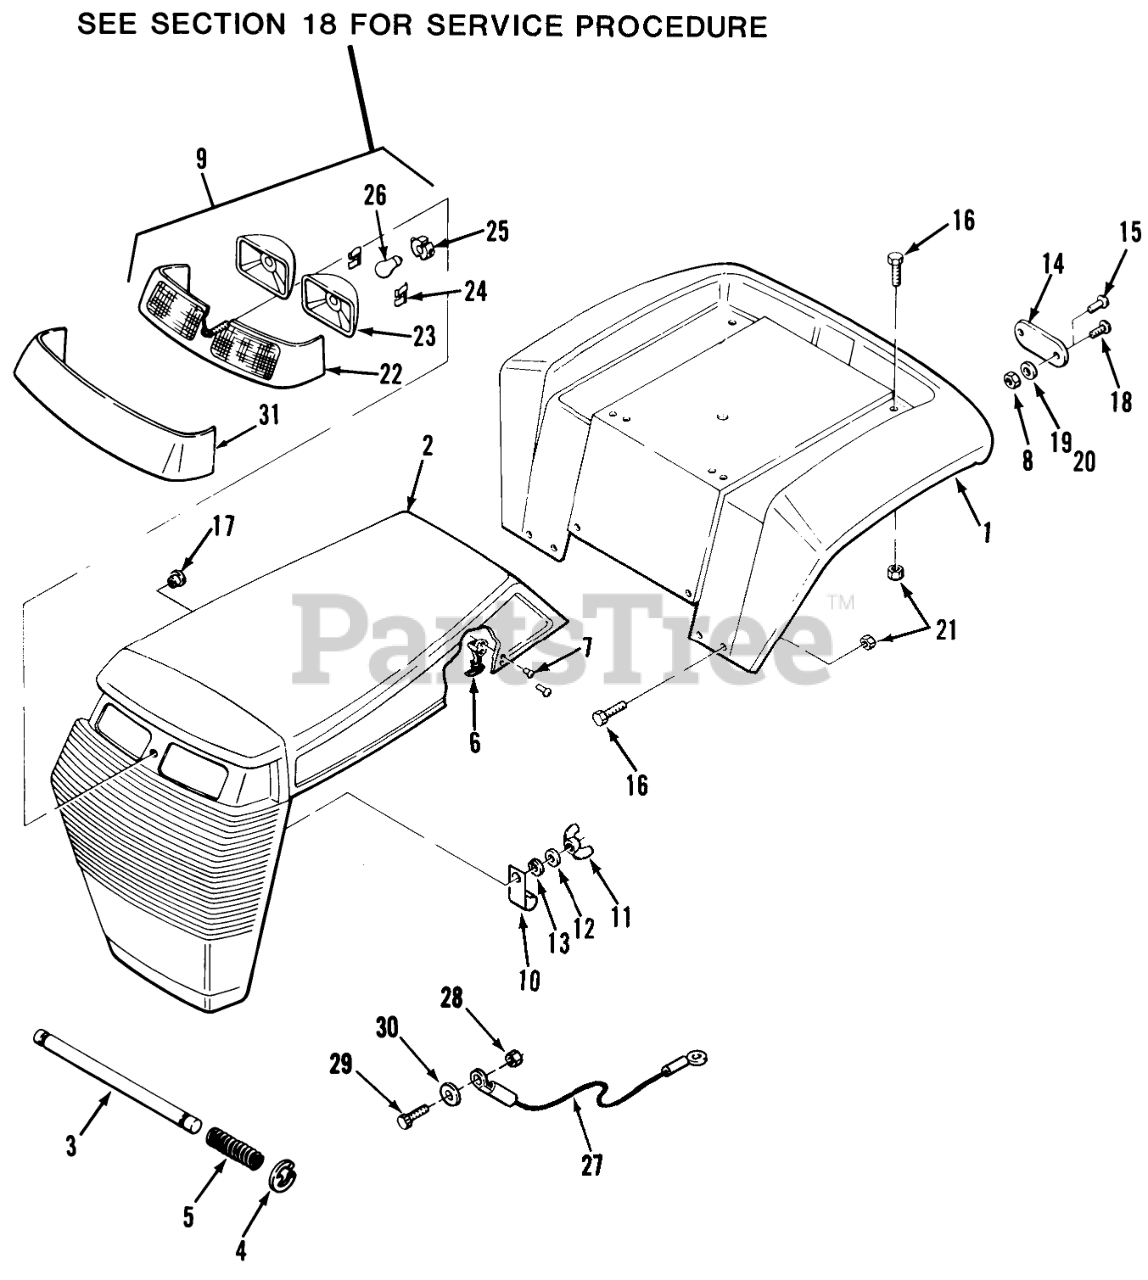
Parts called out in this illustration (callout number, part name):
1	FENDER R
2	Hood & Grill 208-4
2	Hood & Grill 211-4 & 211-5
2	Hood & Grill 212-6
4	E-Ring
5	SPRING
6	ASSY-FLEX DRAW LATCH
7	RIVET
8	Nut
9	Head Light Bar 211-4, 211-5, 212-6 (Includes items 22, 23, 24 & (2) of 26)
10	J-CLIP
11	Nut-Wing
12	WASHER
13	LCKWSHR 1/4 INT TTH
14	Reflector
15	Poprivet
16	Bolt-Carriage
17	BUSHING-NYLON 1.093
18	Screw
19	WASHER
20	Lockwasher
21	Nut
22	Light Bar
23	LIGHT POD
24	RETAINER
25	SOCKET-LIGHT
26	BULB
27	CABLE-HOOD LANYARD
27	Hood Lanyard Cable 211-4 & 211-5
28	Nut
29	Screw-Machine
30	WASHER-BACKING
31	Cover 208-4
